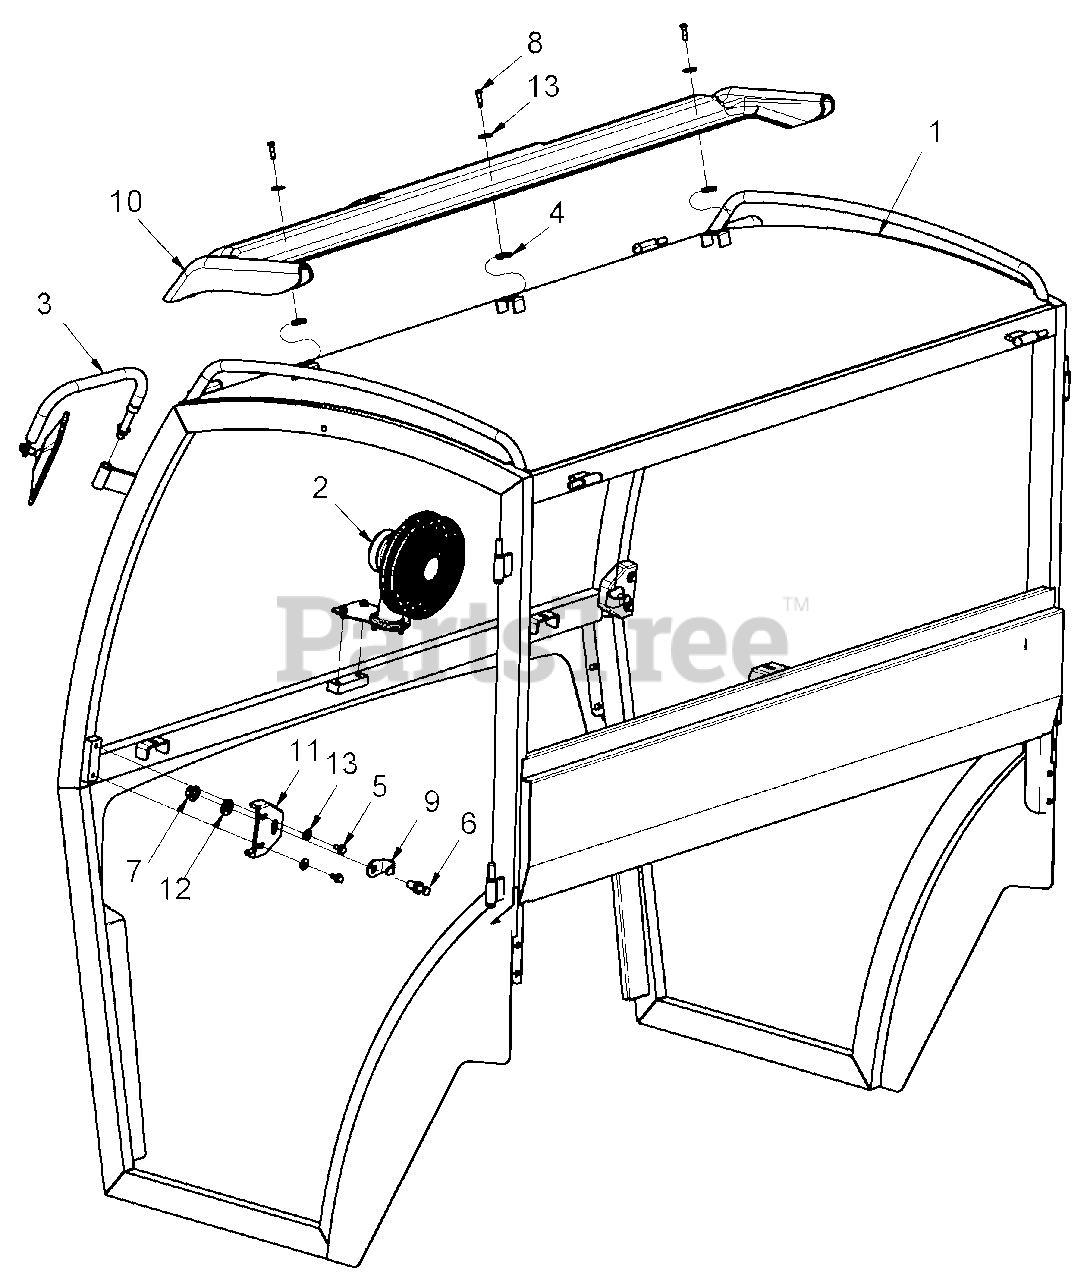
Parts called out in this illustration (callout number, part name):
1	Cab, Steel Truck Hard
2	Fan, Cab
3	Mirror Kit, Cab
4	Nut, Retainer .25-20 x .56
5	Bolt, Serrated Hex Flange Washer Head .25-20 x .5
6	Pin, Striker
7	Nut, Striker Pin
8	Screw, BH 1/4 x 1 1/4 Black
9	Guard, Striker Pin
10	Fascia, Roof
11	Plate, Striker Mounting
12	Washer, Striker Pin
13	Washer, Flat Steel .281 x .62 x .065
